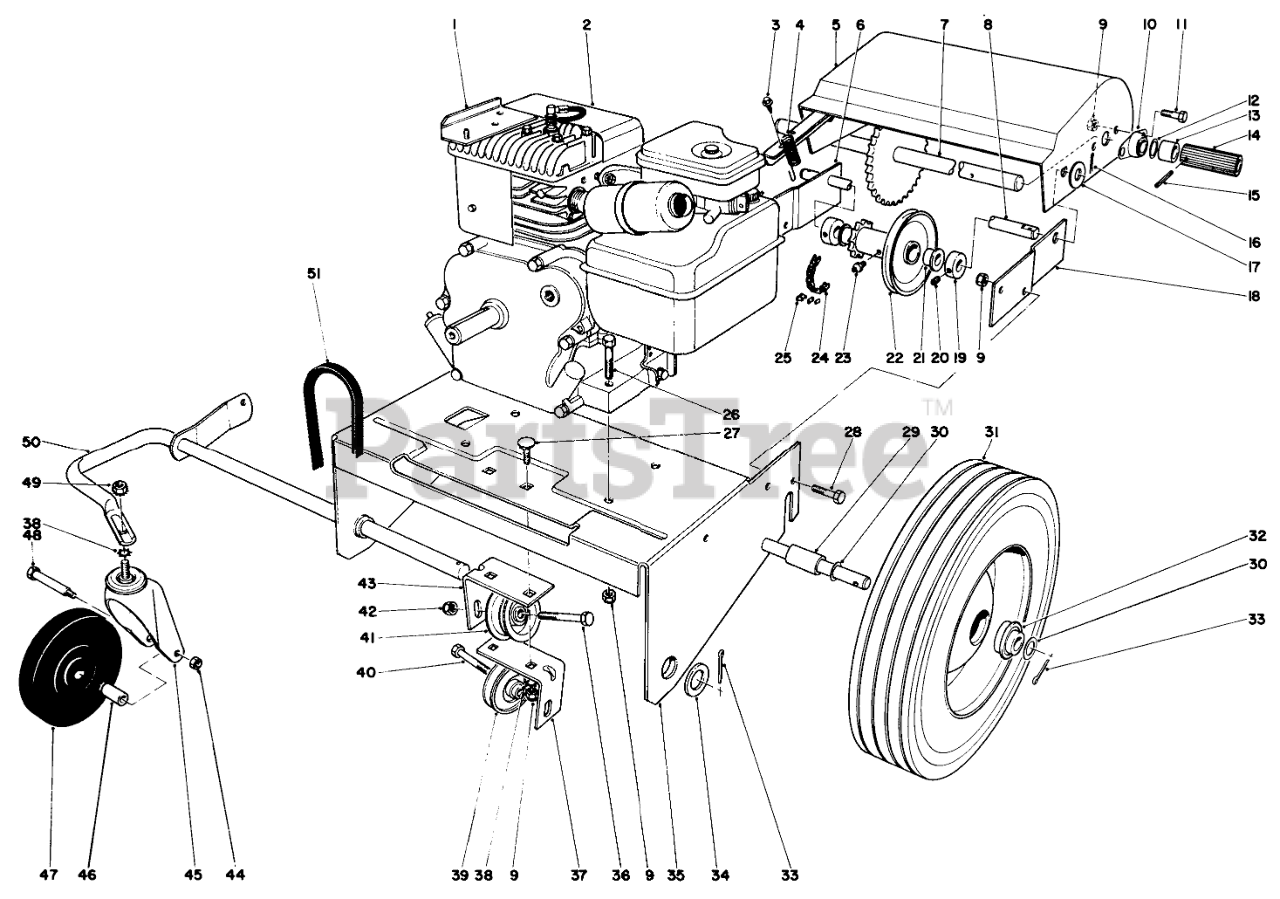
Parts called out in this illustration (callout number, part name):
1	MOUNTING BRKT WA
2	Engine
3	SCREW-HWHTF
4	Spring, Traction
5	GUARD WA
6	Mounting Bracket
7	SHAFT-WHEEL, FRICTION
8	SHAFT-IDLER
9	NUT-LOCK, NI
10	BEARING-MOUNT, FLANGE
11	SCREW-HH
12	WASHER
13	SPACER
14	WHEEL-FRICTION
15	PIN-ROLL, SLOTTED
16	PIN-COTTER
17	WASHER-FLAT
18	Mounting Bracket
19	COLLAR
20	SCREW-SET, HSH
21	BUSHING-FLANGE
22	Idler (Incl. Nos. 21 & 23)
23	FITTING-GREASE
24	Chain Traction
25	LINK-CONNECTING, NO. 35
26	SCREW-HH
27	SCREW-CARR
28	SCREW-HH
29	SPACER-AXLE
30	WASHER
31	Wheel (Incl. No. 32)
32	BEARING
33	PIN-COTTER
34	WASHER-FLAT
35	Engine Plate
36	SCREW-HH
37	Bracket-Idler Mount L.H.
38	WASHER-LOCK
39	PULLEY-IDLER
40	SCREW-HH
41	PULLEY-IDLER
42	NUT-LOCK, NI
43	Bracket-Idler Mount R.H.
46	Wheel Bushing
47	Wheel
50	Front Wheel Support
51	BELT-V
